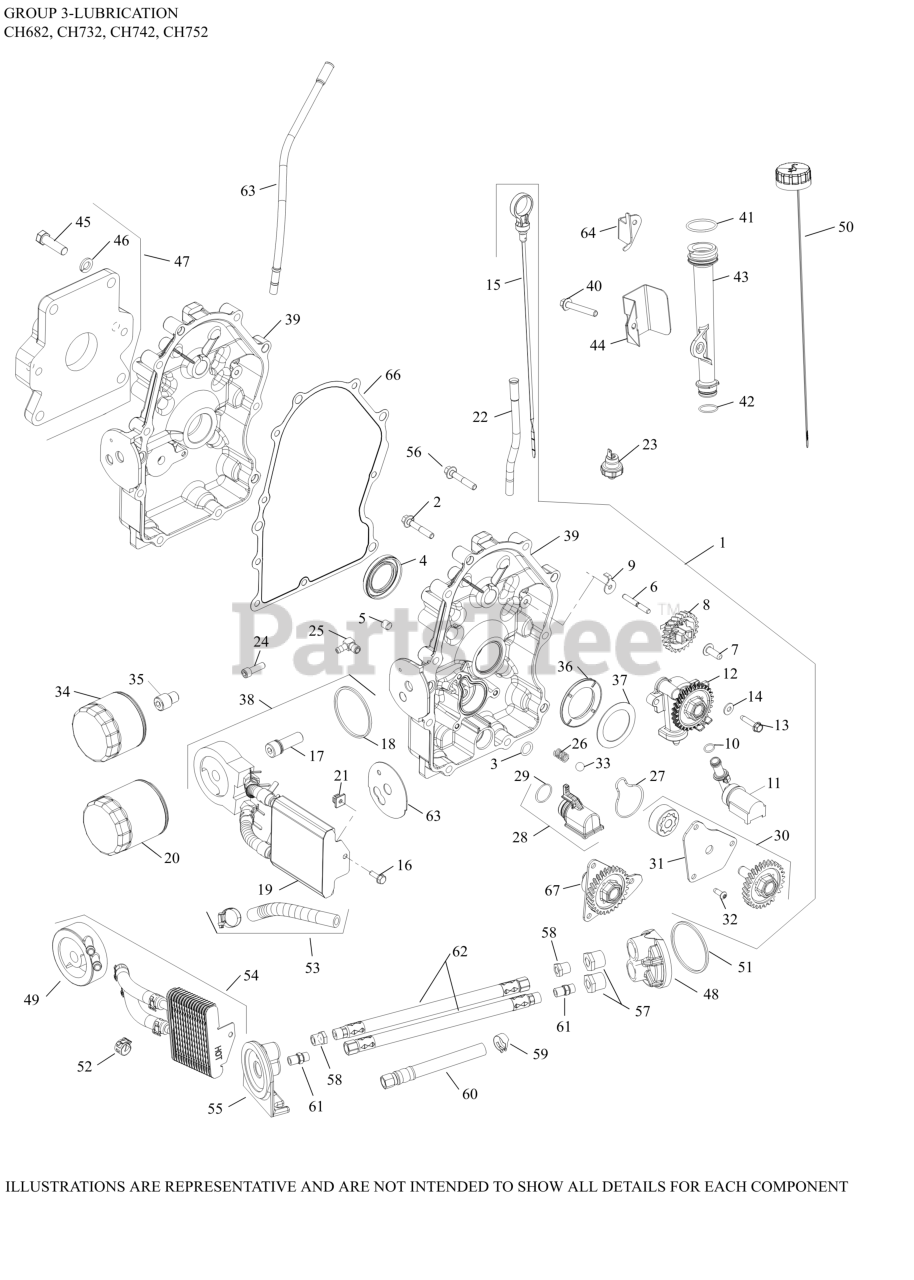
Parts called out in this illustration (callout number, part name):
1	KIT, CLOSURE PLATE ASSY
2	SCREW, FLG M8X1.25X45
5	PLUG, CTSK PIPE 1/8"
6	SHAFT, GOVERNOR GEAR
7	PIN, GOVERNOR REGULATING
8	KIT, GOVERNOR GEAR W/PIN
9	TAB, LOCKING
10	O-RING, OIL PICK-UP
11	PICK-UP, OIL
12	KIT, OIL PUMP ASSEMBLY-(#DSC)
13	SCREW, THREAD FORMING
14	WASHER, FLAT 1/4" (O.D. 5/8")
16	SCREW, TAP M6X1.7X18
17	NIPPLE, OIL FILTER - (#2413608S)
18	O-RING, OIL COOLER
20	OIL FILTER
21	NUT, PLASTIC - BLACK
22	KIT, DIPSTICK/DIPSTICK TUBES
23	SENSOR, OIL PSI
26	SPRING, COMPRESSION
27	SEAL, OIL PUMP COVER
28	PICK-UP ASSEMBLY, OIL
29	O-RING, OIL PICK-UP
30	PUMP ASSEMBLY, OIL
31	COVER, OIL PUMP
32	SCREW, BUTTON HEAD
33	PRESSURE RELIEF BALL
49	ADAPTER, OIL FILTER (CV EFI)
52	CLAMP, HOSE LOW PROFILE
53	KIT, HOSE 140MM
54	COOLER, OIL & DIVERTER ASSEMBLY
56	SCREW, HEX FLANGE
